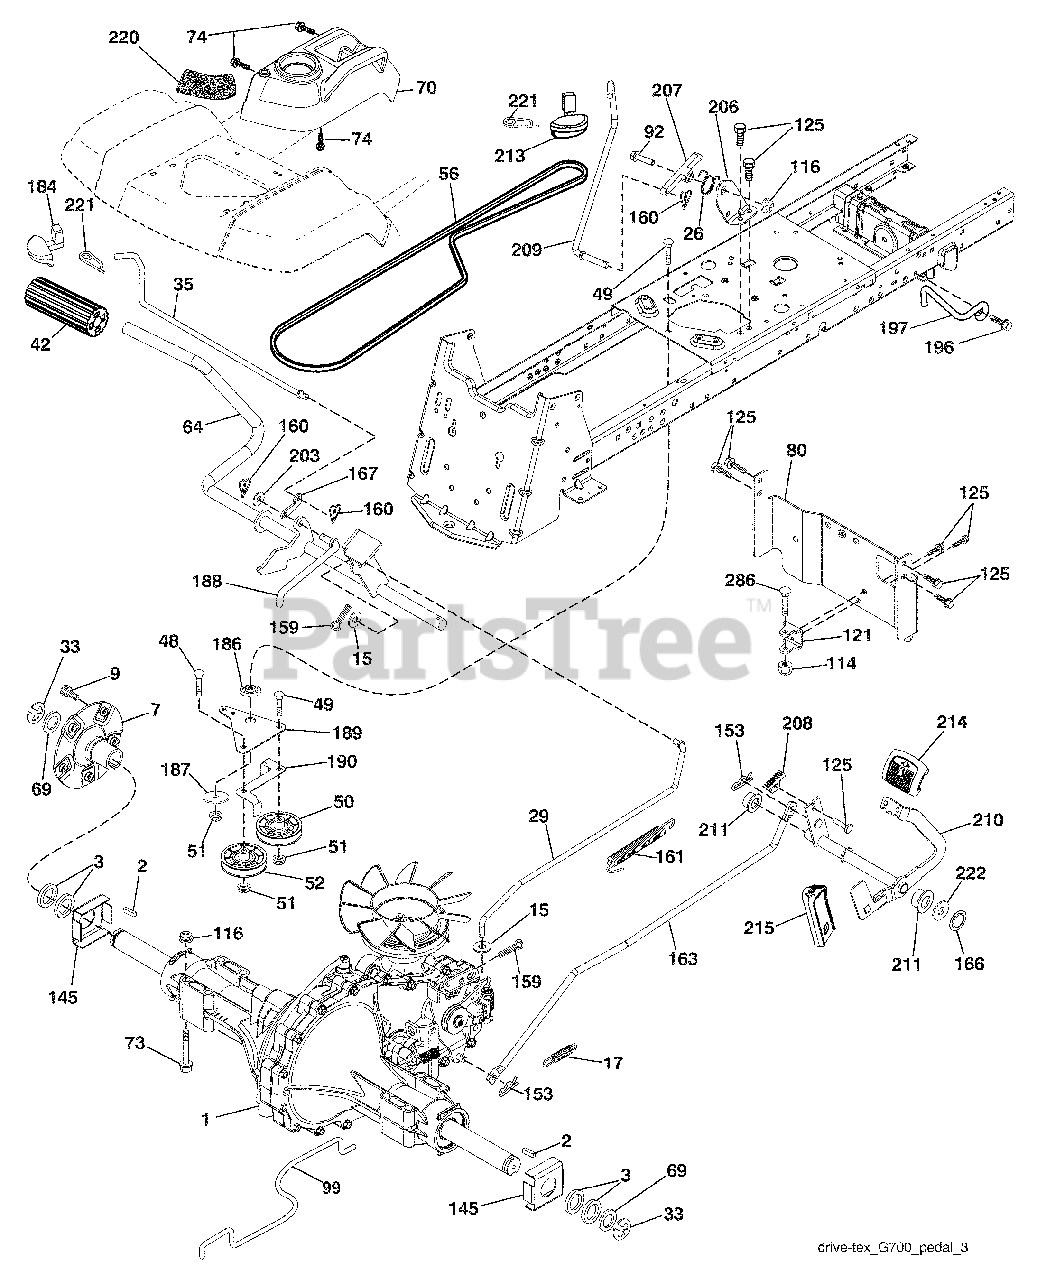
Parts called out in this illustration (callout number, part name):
2	Key 1/4 x 2.5
3	Washer Thrust Axle Hardened
7	Hub Asm. Wheel
9	Bolt Hub Wheel
15	Washer 13/32 x 13/16 x 16 Ga.
17	Spring, Brake
26	Spring Return Cruise
29	Rod, Brake
35	Rod, Brake, Park
42	Cover, Foot Pedal
48	Bolt 3/8-16 x 1-1/2 Gr. 5
50	Pulley Idler Flat
51	Lock Nut 3/8-16
52	Idler V-Groove 910" Offset
56	V-Belt, Drive
64	Shaft Asm. Pedal Brake Control
69	Washer 1-1/32 x 1-5/8 x 16 Ga.
70	Console Shift
73	Bolt Hex 5/16-18 x 3 Gr. 5
74	Screw 1/4 x 1/2
80	Strap Torque
92	Bolt 5/16-18 x 1/2
99	Spring Bypass
114	Nut Lock Hex W/Ins. 5/16-18 unc
116	Nut Lock Hex Flange 5/16-18
121	Bracket Strap Torque
125	Screw 5/16-18 x 3/4
145	Washer Axle Flange
153	Retainer Spring
159	Pin Cotter 1/8 x 3/4
160	Retainer Clip
161	Spring, Return, Clutch
163	Rod Pedal Control
166	Nut Push .625
167	Latch Brake Parking
184	Handle Parking Brake
186	Spacer Retainer
187	Washer
188	Link Clutch Ground Drive
189	Bellcrank Ground Drive
190	Keeper Bellcrank Ground Drive
196	Screw 3/8-16 x 1
197	Bracket Clutch Anti-Rotation
203	Washer 11/32 x 11/16 x 16 Ga.
206	Bracket Mount Latch Cruise
207	Latch Control Cruise
208	Gear Sector Control Cruise
209	Rod Control Cruise
210	Rocker Asm. Pedal Control
211	Bearing Nylon
213	Knob Control Cruise
214	Pedal Forward
215	Pedal Reverse
220	Reflector LH
221	Retainer Spring Clip Handle
222	Washer 21/32 x 1-1/4 x 10 Ga.
286	Bolt 5/16-18 x 2.75
